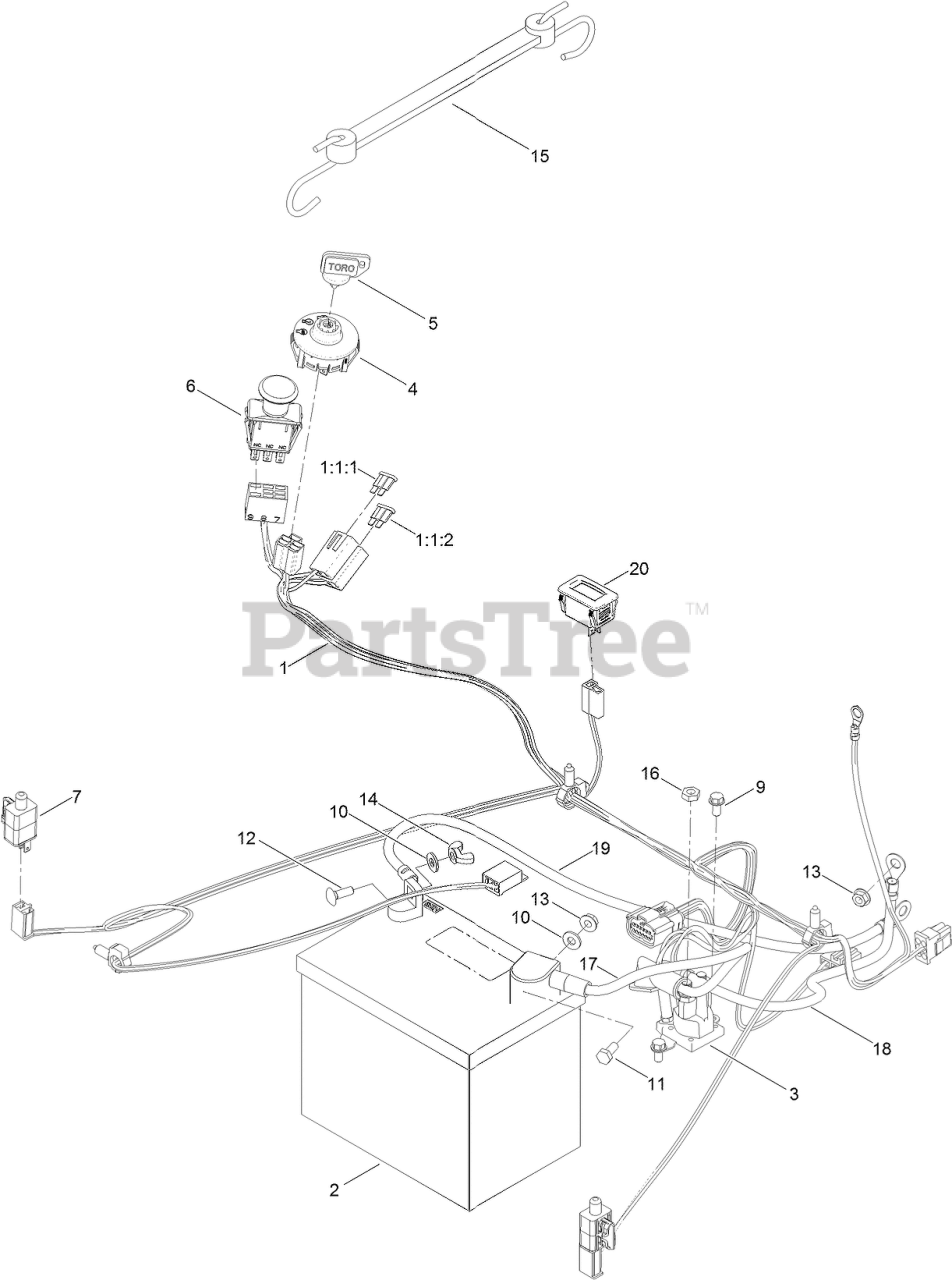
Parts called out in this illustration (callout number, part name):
1	HARNESS-WIRE
1:1:1	FUSE-BLADE, 30 AMP
1:1:2	FUSE-BLADE, 25 AMP
2	BATTERY
3	SOLENOID
4	SWITCH-IGNITION
5	KEY-IGNITION
6	SWITCH-PTO
7	SWITCH
9	SCREW-HWH
10	WASHER-FLAT
11	SCREW-HH
12	BOLT-CARR
13	NUT-HF
14	NUT-WING
15	HOLDDOWN-BATTERY
16	NUT-JAM
17	CABLE-BATTERY, RED
18	CABLE-BATTERY, POSITIVE
19	CABLE-BATTERY, BLACK
20	HOURMETER
